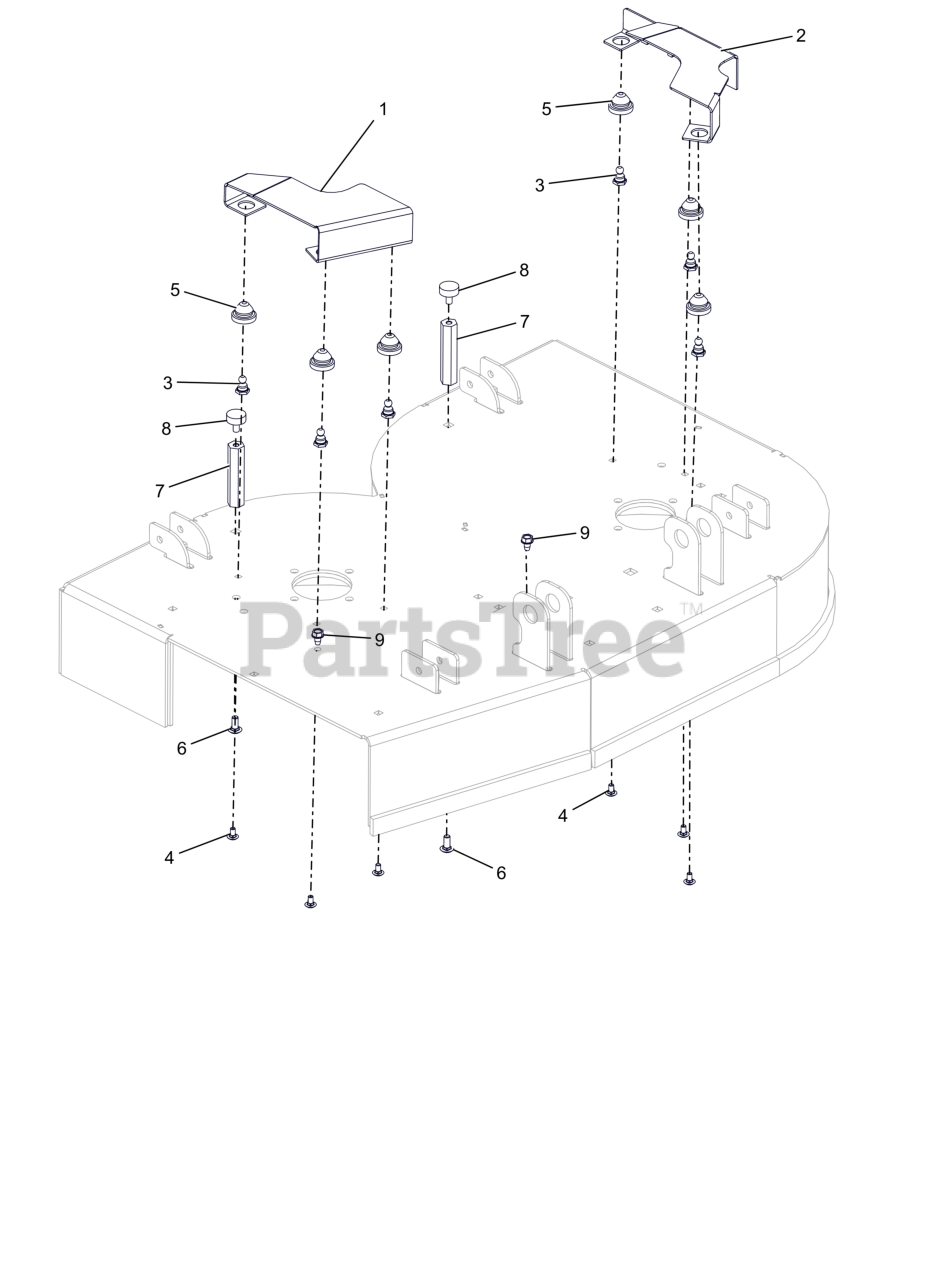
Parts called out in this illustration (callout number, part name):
1	GUARD, RH DECK BELT (RED)
2	GUARD, LH DECK BELT (RED)
3	STUD, BALL FEMALE .250-20 THREAD
4	BLT, RHSSN.25-20X.500 G5 ZCC
5	COUPLING, RUBBER PUSH-IN
6	BLT, RHSSN.31-18X.750 G5 ZCC
7	NUT, .31-18 x 3.500 LG COUPLING
8	BUMPER, RUBBER
9	SCR,TAP .312-18X.50 HWH TR ZCC
